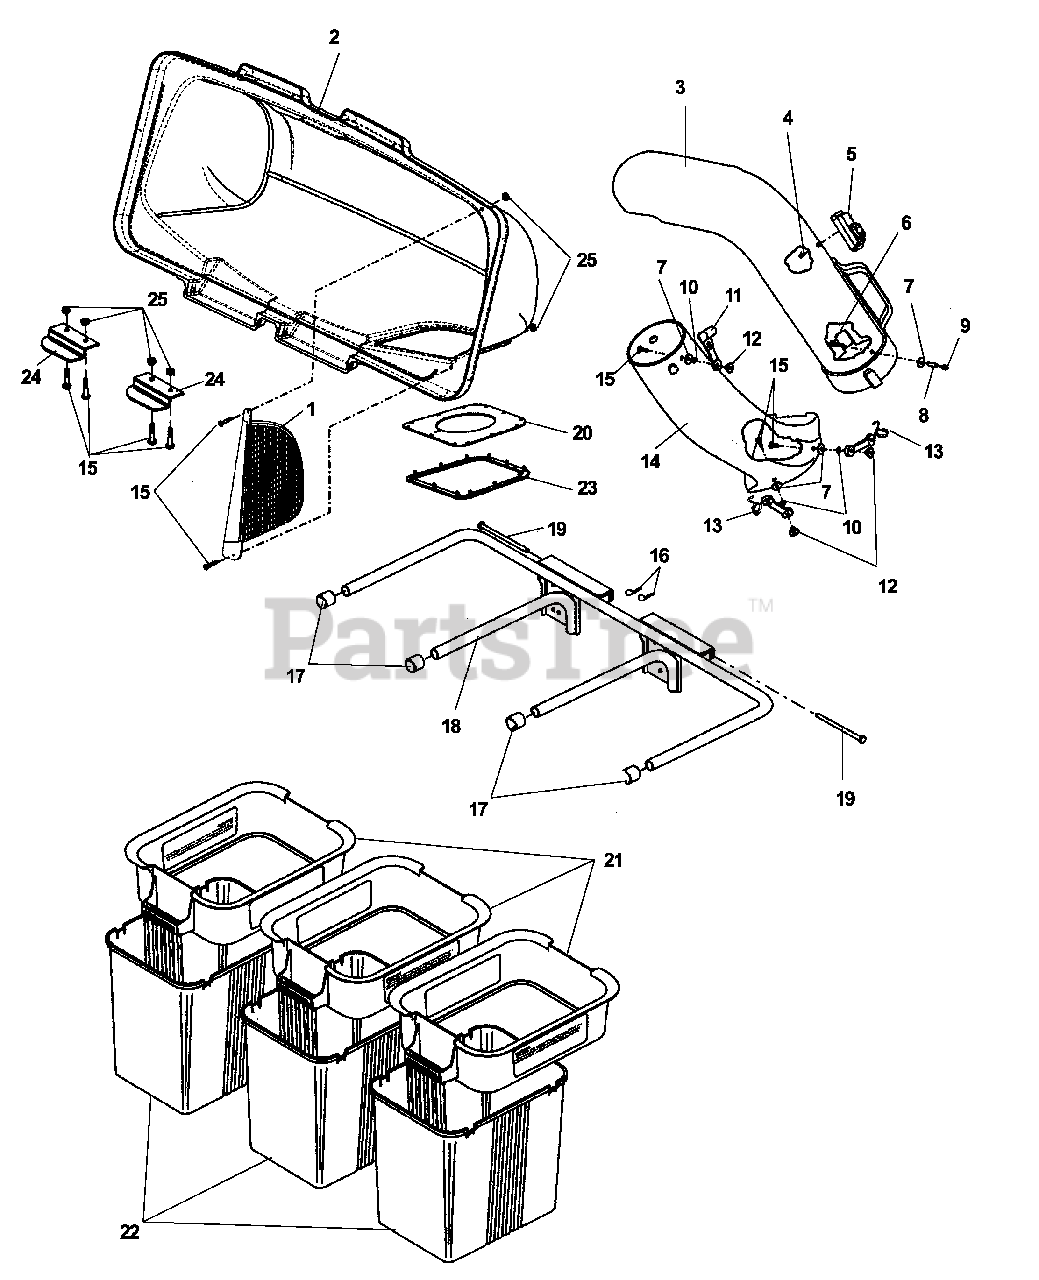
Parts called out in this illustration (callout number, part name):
1	Screen, cover
3	Chute, upper,
4	Screw, #10-14 x 1/2, special
5	Dump bag indicator
6	Screw, #10-24 x 1 1/8
7	Washer, 3/16 x 3/4 x 16 Ga.
8	Spacer, split
9	Nut, #10-24, acorn
10	Lockwasher, 3/16
11	Latch, chute
12	Nut, weld
13	Latch, assembly
14	Chute, lower, 54" deck
15	Screw, #10-24 x 5/8
16	Spring, retainer
17	Plug, tubing end
18	Bagger, frame
19	Pin, hinge
20	Gasket, cover
21	Container, top
22	Container, bottom
23	Seal, cover
24	Handle, bagger cover
25	Nut, #10-24, crownlock
